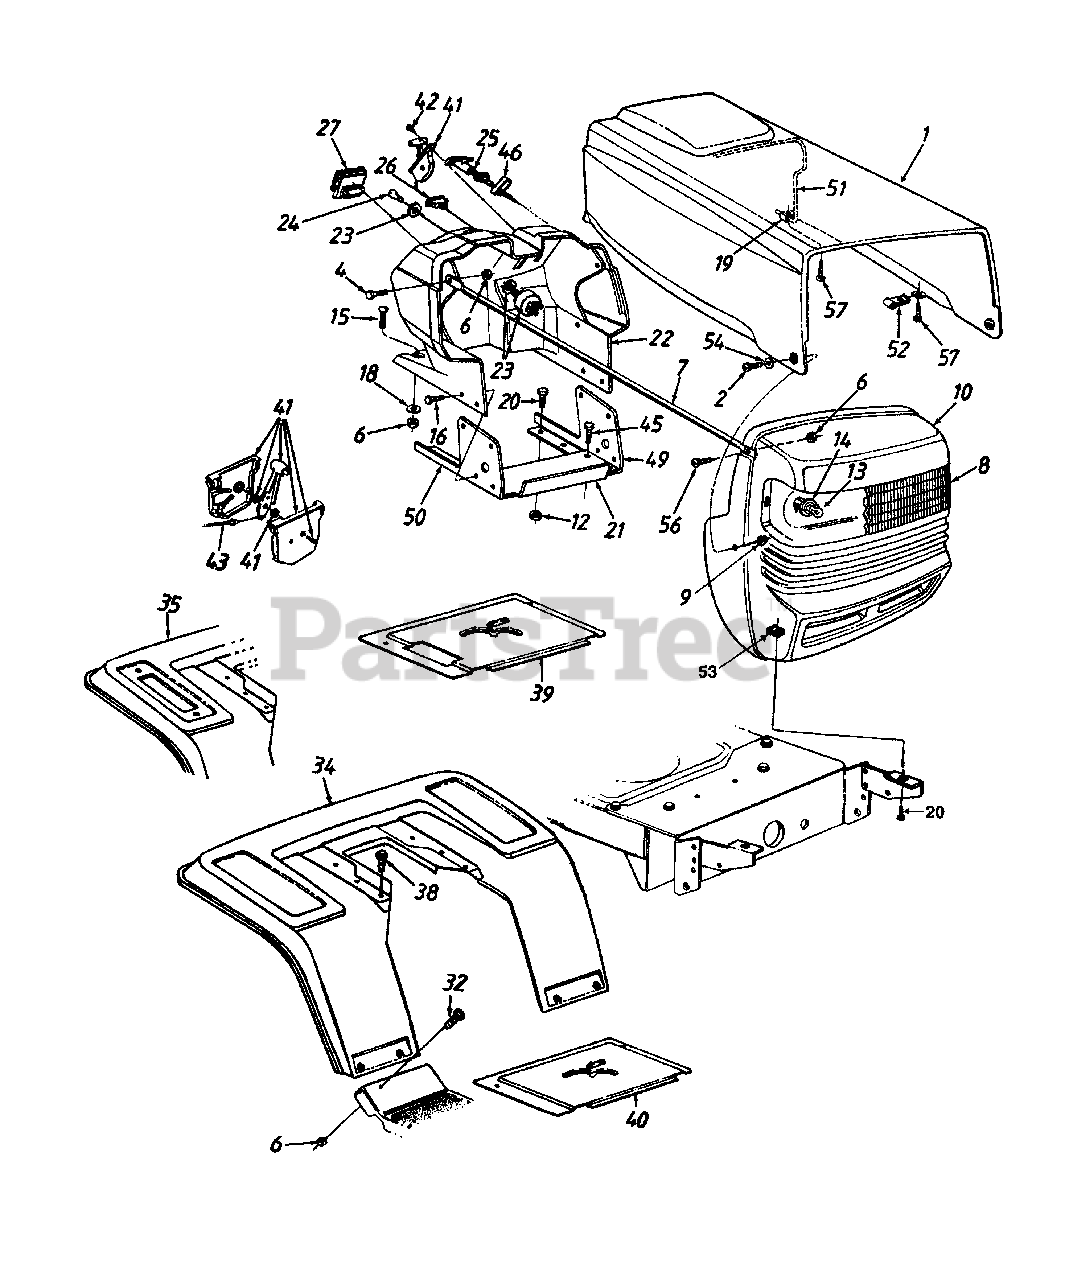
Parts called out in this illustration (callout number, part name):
4	Hex Bolt 1/4-20 x .88" Lg.
6	Hex Sems Nut 1/4-20 Thd.
9	Flange L-Nut 1/4-20 Thd.
12	Hex Sems Nut 5/16-18 Thd.
13	Lamp
14	Socket
15	Carriage Bolt 1/4-20 x .75" Lg.
16	Hex Wash. Hd. TT-Tap Scr. 1/4-20 x .5" Lg.
18	Bolt Retainer 1/4" I.D.
19	i Speed Nut #10-24 Thd.
20	Hex Bolt 5/16-18 x .75" Lg.
23	Ignition Switch
24	Ignition Key
25	Choke Control 23" Lg.
26	Light Switch
27	Ammeter
32	Truss Mach. Scr. 1/4-20 x .5" Lg.
41	Throttle Box Ass'y.
42	Truss Mach. AB-Tap Scr.#10 x .5" Lg.
43	Throttle Control Wire 18.5" Lg.
45	Hex Wash. Hd. B-Tap Scr. 5/16-18 x .5" Lg.
46	Choke Retainer
52	Flat Fastener (Special)
53	U-Nut 5/16-18 Thd.
54	Spr. Wash. .39" I.D. x .62" O.D.
56	Pan Hd. Scr. 1/4-20 x .75" Lg.
57	Truss Mach. Scr. #10-24 x .5" Lg.
